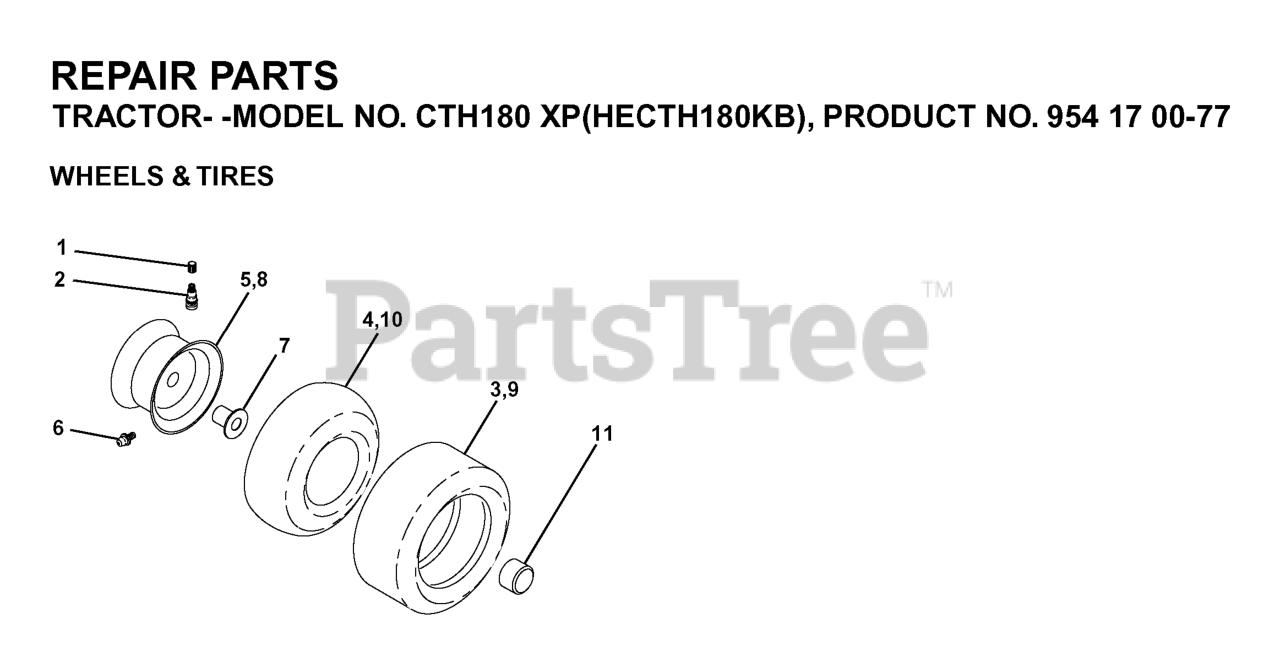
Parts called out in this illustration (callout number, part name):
2	VALVE STEM LT
3	TIRE HEAVY DUTY
4	TUBE.5.3/4.5/6
5	RIM ASM 6" FRONT SILVER
6	FITTING LT
7	BEARING T
8	RIM ASM 8" REAR SILVER
9	TIRE.20X8-8.TURF.SAVER
10	TUBE
11	CAP, AXLE BLK
